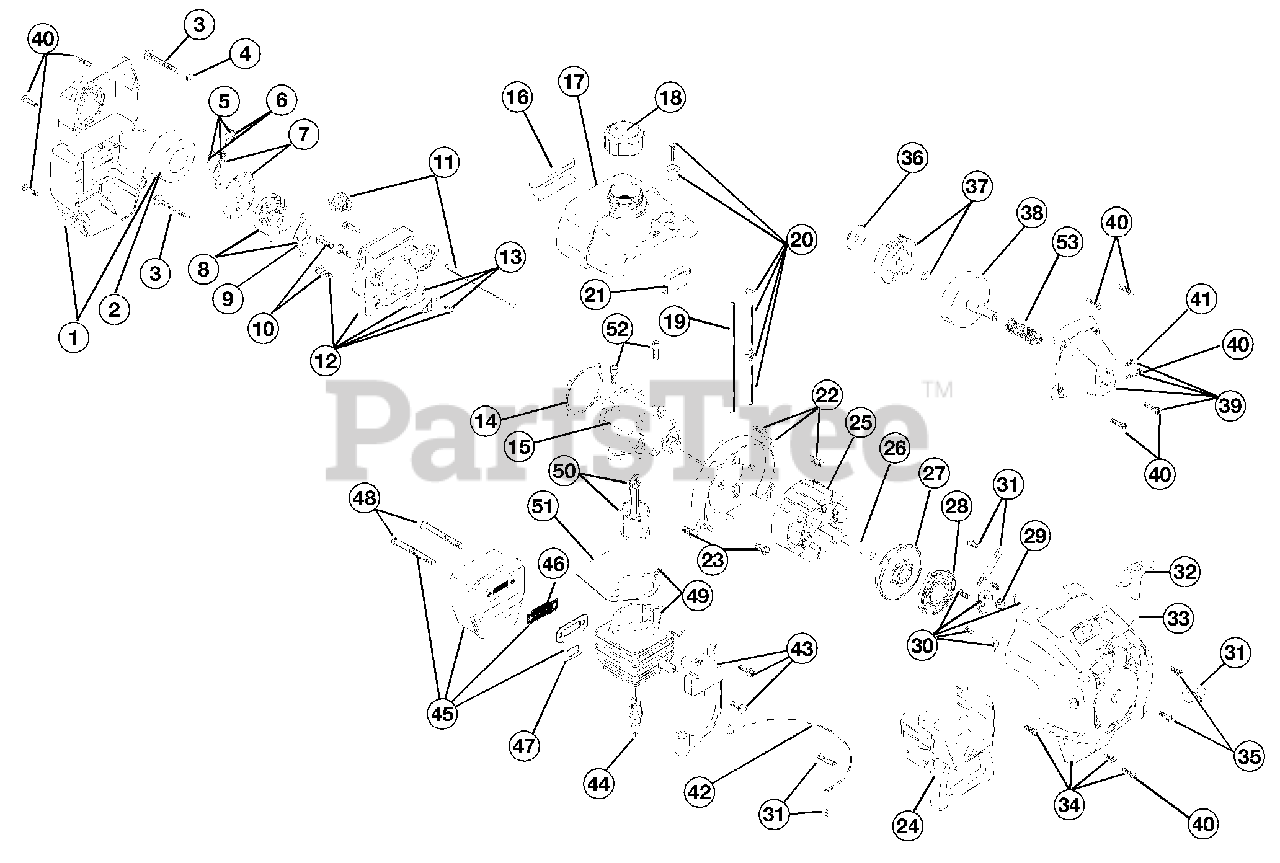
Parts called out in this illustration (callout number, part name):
1	Air Cleaner/Muffler Cover Assembly
2	Air Cleaner Filter
3	Carburetor Mounting Screw Assembly
4	Wavey Washer
5	Choke Lever Assembly
6	Choke Knob and Screw
7	Choke Lever and Plate
8	Carburetor Assembly
9	Carburetor Gasket
10	Carb Mount Screw
11	Primer and Hose Assembly
12	Carb Mount Assembly
13	Reed Assembly
14	Carburetor Mount Gasket
15	Crank Case Service Assembly
16	Rear Mounting Pad
17	Fuel Tank Assembly
18	Fuel Cap Assembly
19	Fuel Return Line
20	Fuel Line Assembly
21	Front Mounting Pad
22	Shroud Assembly
23	Shroud Screw
24	Shroud Extension and Stand
25	Flywheel Assembly
27	Recoil Pulley Assembly
28	Recoil Spring
29	Rope Guide
30	Pulley Retainer Assembly
31	Switch Assembly
32	Pull Handle
34	Starter Housing Assembly
35	Housing Screw
36	Clutch Washer
37	Clutch Rotor Assembly
38	Clutch Drum Assembly
39	Clutch Cover Assembly
41	Anti-Rotation Screw
42	Wire Lead
43	Module Assembly
44	Spark Plug
45	Muffler Assembly
46	Spark Arrestor Screen
47	Exhaust Gasket
48	Muffler Mounting Bolt
49	Cylinder Assembly
50	Piston and Rod Assembly
51	Cylinder Gasket
52	Cylinder Bolt
